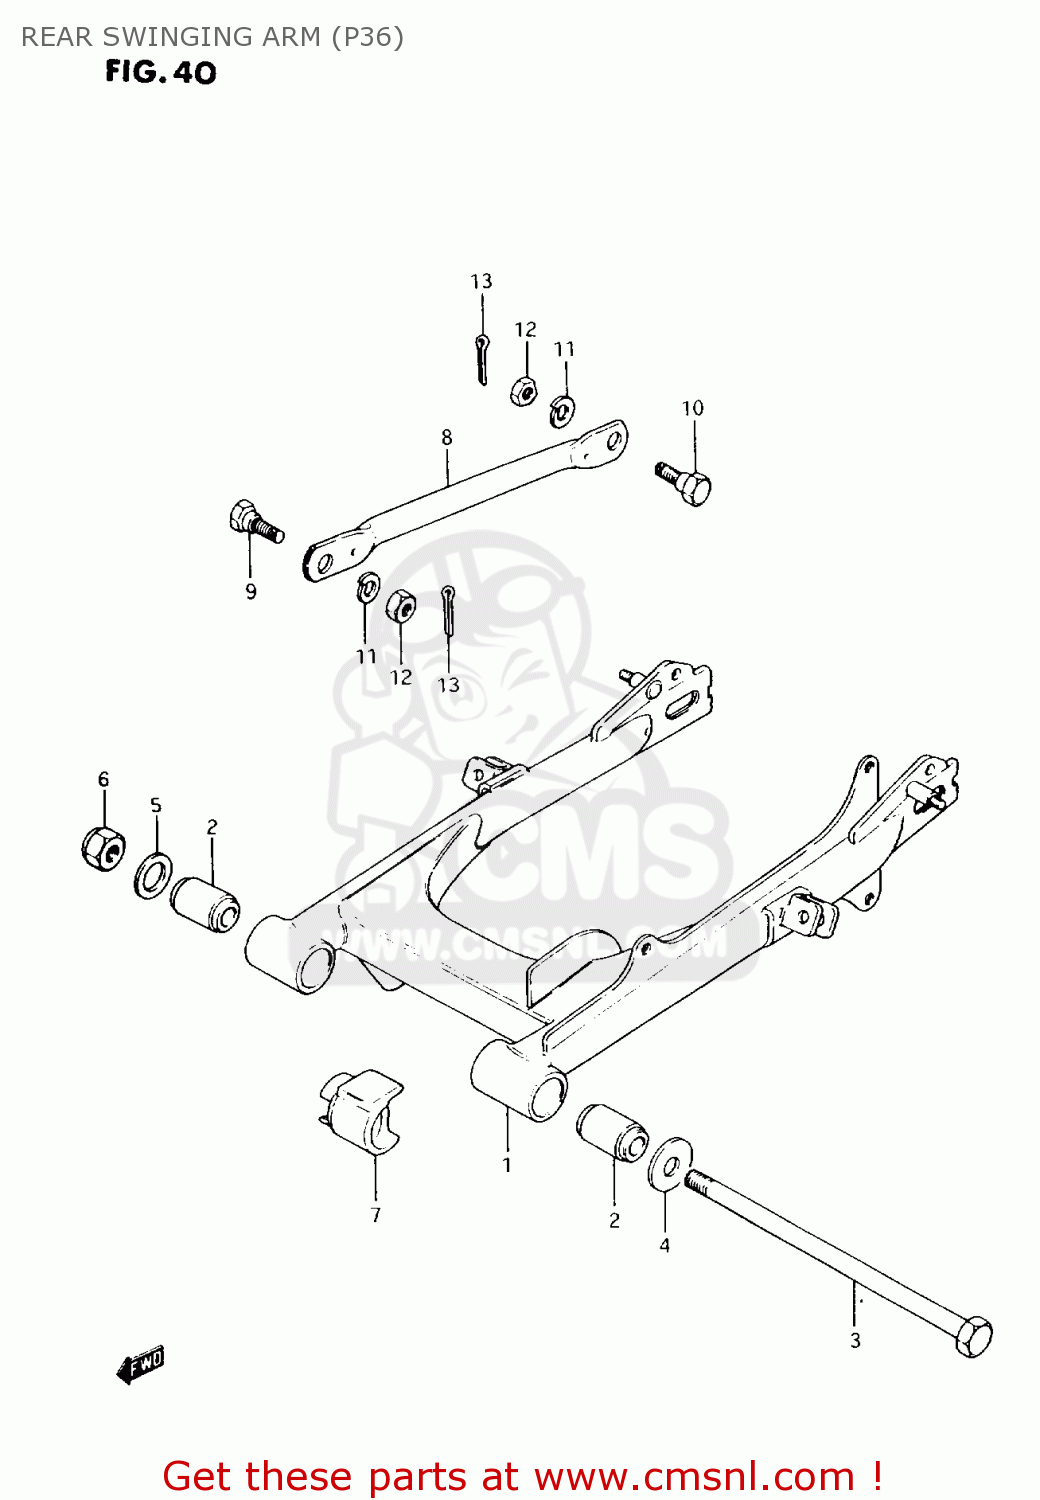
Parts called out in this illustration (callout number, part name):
1	SWINGING ARM SET (BLACK)
2	BUSH(12X24X44)
3	SHAFT,RR SWINGINGARM PIVOT
4	WASHER(12.5X32X2.3)
5	WASHER
6	NUT 12MM
7	BUFFER,DEFENSE
8	TORQUELINK,RR
9	BOLT(8X22.5)
10	BOLT(8X22.5)
11	WASHER,LOCK
12	NUT
13	PIN 20X20
